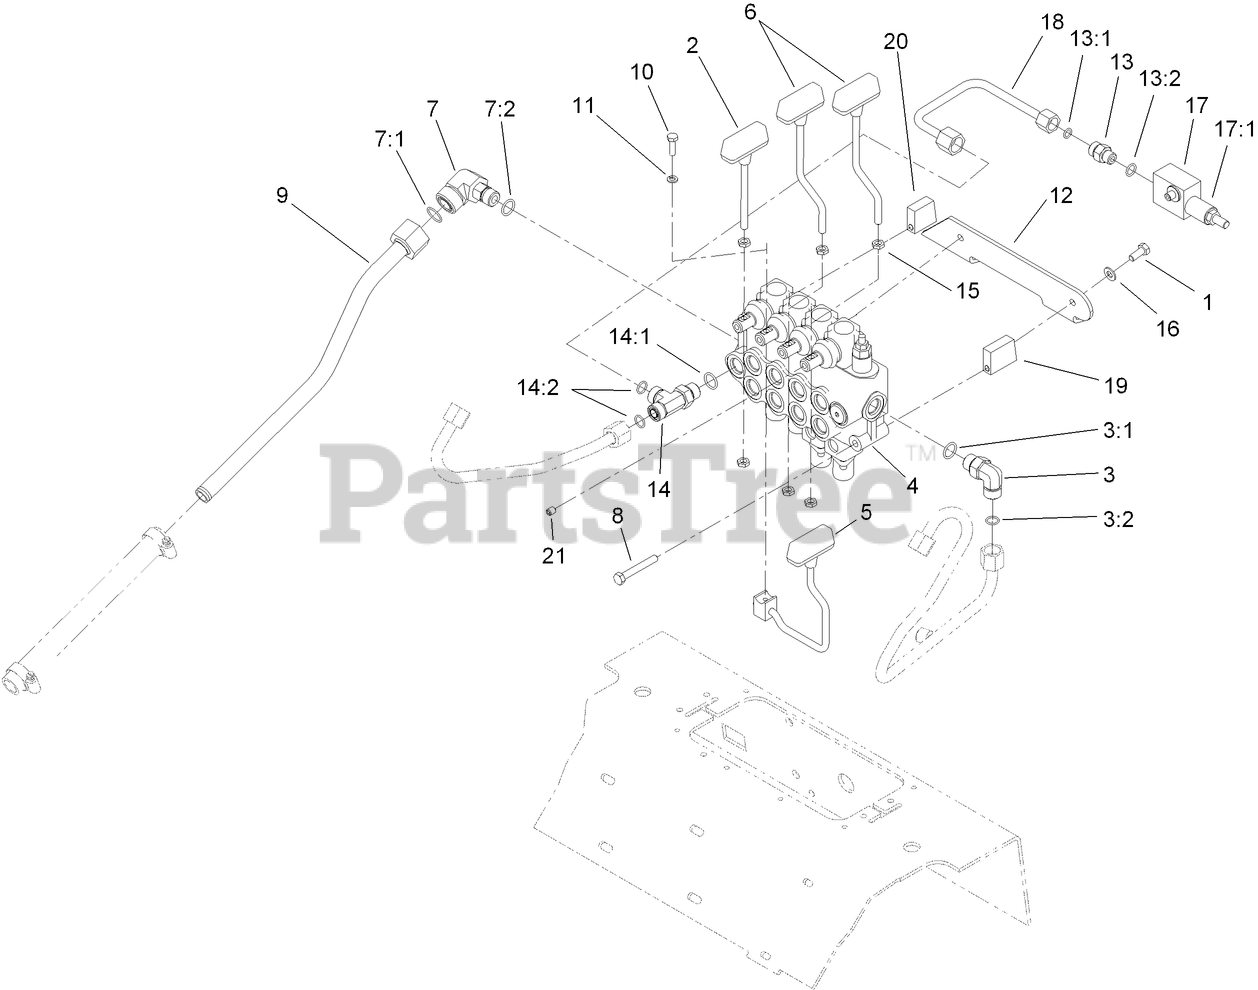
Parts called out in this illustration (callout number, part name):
1	SCREW-HH
2	LEVER-CYLINDER
3	FITTING-ELBOW-90 DEG
3:1	O-RING
3:2	O-RING
4	HYD FOUR SPOOL VALVE ASM
5	LEVER-CONTROL
6	LEVER-DRIVE
7	FITTING-HYD, 90 DEG
7:1	O-RING
7:2	O-RING
8	SCREW-HH
9	TUBE-TANK, HYD
10	SCREW-HSH
11	SPACER
12	BRACKET-COVER, MOUNT
13	FITTING-STRAIGHT
13:1	O-RING
13:2	O-RING
14	FITTING-TEE
14:1	O-RING
14:2	O-RING
15	NUT-HEX
16	WASHER-PLAIN
17	RELIEF VALVE ASM
17:1	CARTRIDGE-VALVE, RELIEF
18	LINE-HYD
19	SPACER-LOWER
20	SPACER-UPPER
21	SCREW-SET, HSH
